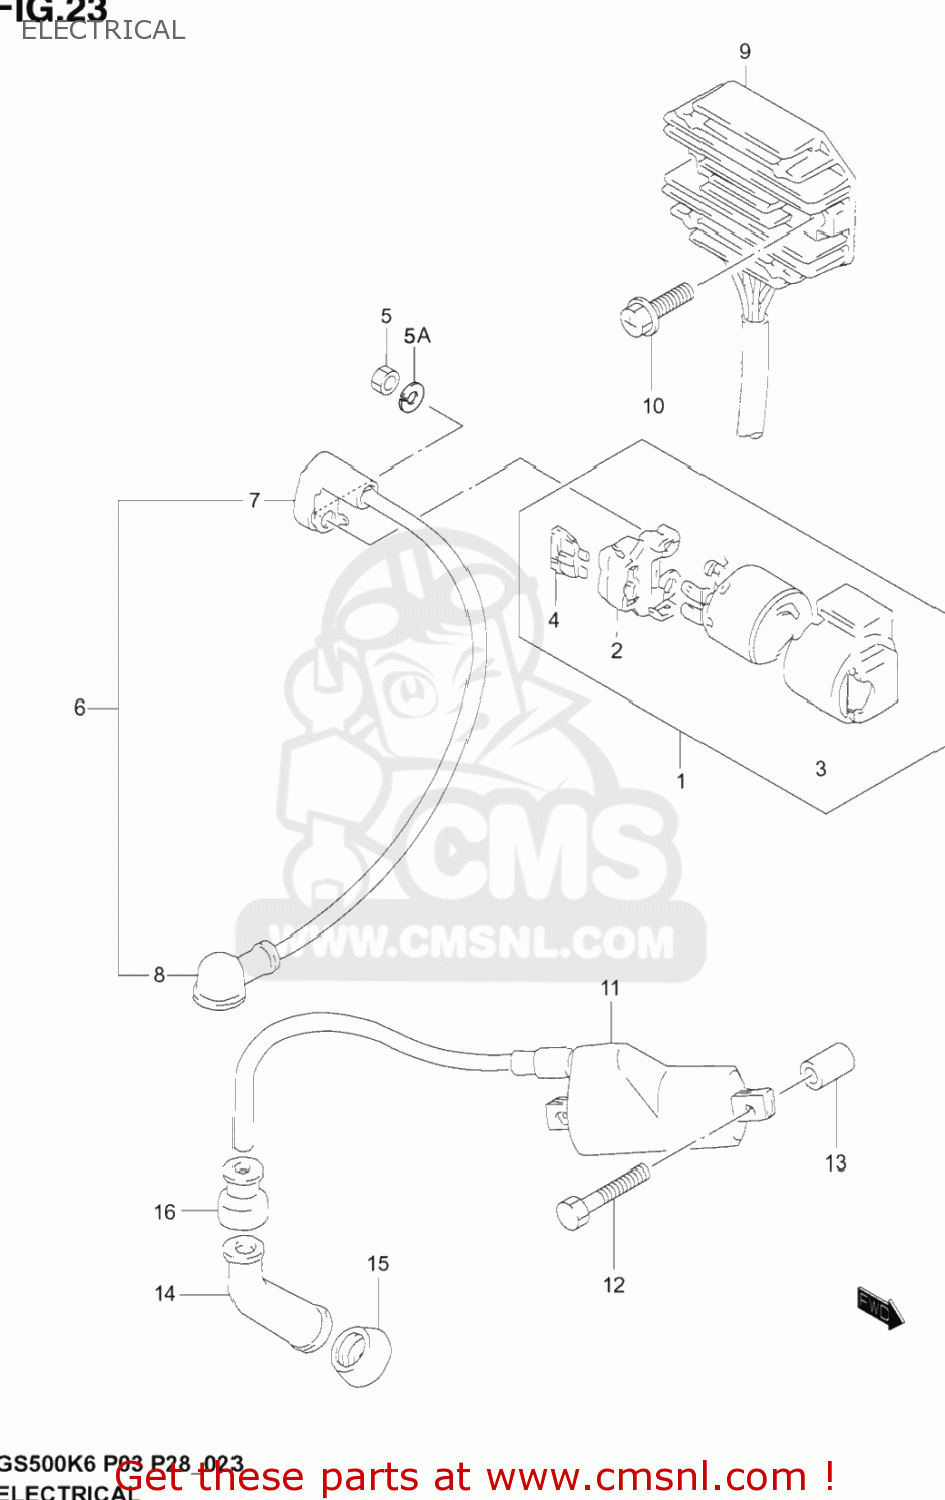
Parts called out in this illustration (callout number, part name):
1	RELAY ASSY,STARTING MOTOR
2	TERMINAL,RELAY
3	BRACKET,STARTING MOTOR RELAY
4	FUSE(20A)
5	NUT
5A	WASHER
6	WIRE,STARTER MOTOR LEAD
7	CAP,STARTER RELAY TERMINAL
8	CAP,STARTER MOTOR LEAD
9	RECTIFIER ASSY
10	BOLT
11	COIL ASSEMBLY,IGNITION
12	BOLT
13	SPACER(6.2X12X16)
14	CAP ASSY,SPARK PLUG
15	SEAL,SPARK PLUG
16	SEAL,HIGH TENSION CORD
